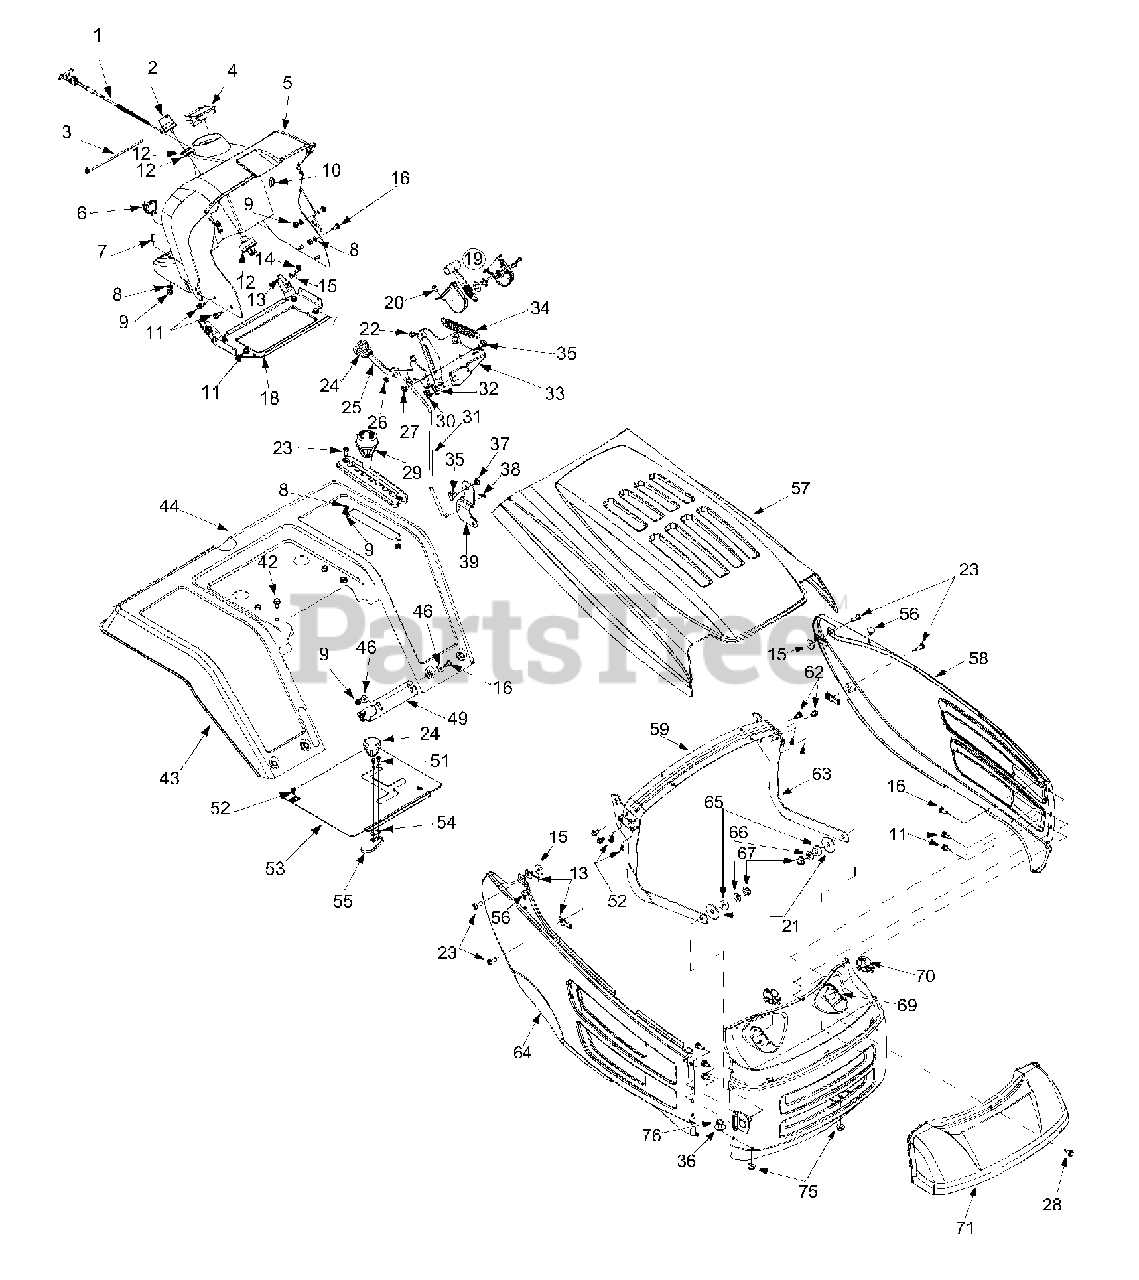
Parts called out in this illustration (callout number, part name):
1	Choke Cable
2	Ignition Key
3	Cable Tie
4	Ammeter
5	Dash Panel
6	Light Switch
7	Carriage Bolt 1/4-20 x 1" Lg.
8	L-Washer 1/4" I.D.
9	Hex Nut 1/4-20 Thd.
10	Choke Retainer
11	Hex Washer Hd. AB-Tapp Scr.
12	Ignition Switch
13	Speed Nut 1/4-20 Thd.
14	Hex Washer Hd. TT-Tapp Scr.
15	Flat Washer 1/4" I.D.
16	Hex Bolt 1/4-20 x .62" Lg.
20	Truss Mach. AB-Tap Scr.
21	Flat Washer
22	Truss Mach. AB-Tap Screw 0.62"
23	Pan Hd. Mach. Scr. 1/4-20 x 0.75"
24	Knob
25	PTO Lever
26	Speed Cap Nut
27	Hex L-Nut 5/16-18 Thd.
28	BSD Screw #10-16 x 0.5"
30	Hex Washer Hd. AB-Tap Scr.
31	Deck Connection Rod
32	Switch Plate
35	Shld. Bolt 1.62" Lg.
37	Hex L-Nut 5/16-18 Thd.
38	Hairpin Clip
39	Control Deck Pivot Bracket
42	Hex Washer Hd. AB-Tapp Scr.
46	Bell Washer 1/4" I.D.
52	Truss Hd. B-Tapp Scr.
55	Spring Switch
56	Rubber Bumper
62	Hex Washer Hd. TT-Tap Scr.
63	Hood Hinge Bracket LH
66	Spring Washer
67	Flange L-Nut 3/8-16 Thd.
69	Socket
70	Lamp
71	Lens
76	Hex Bolt 5/16-18 x 0.75"
